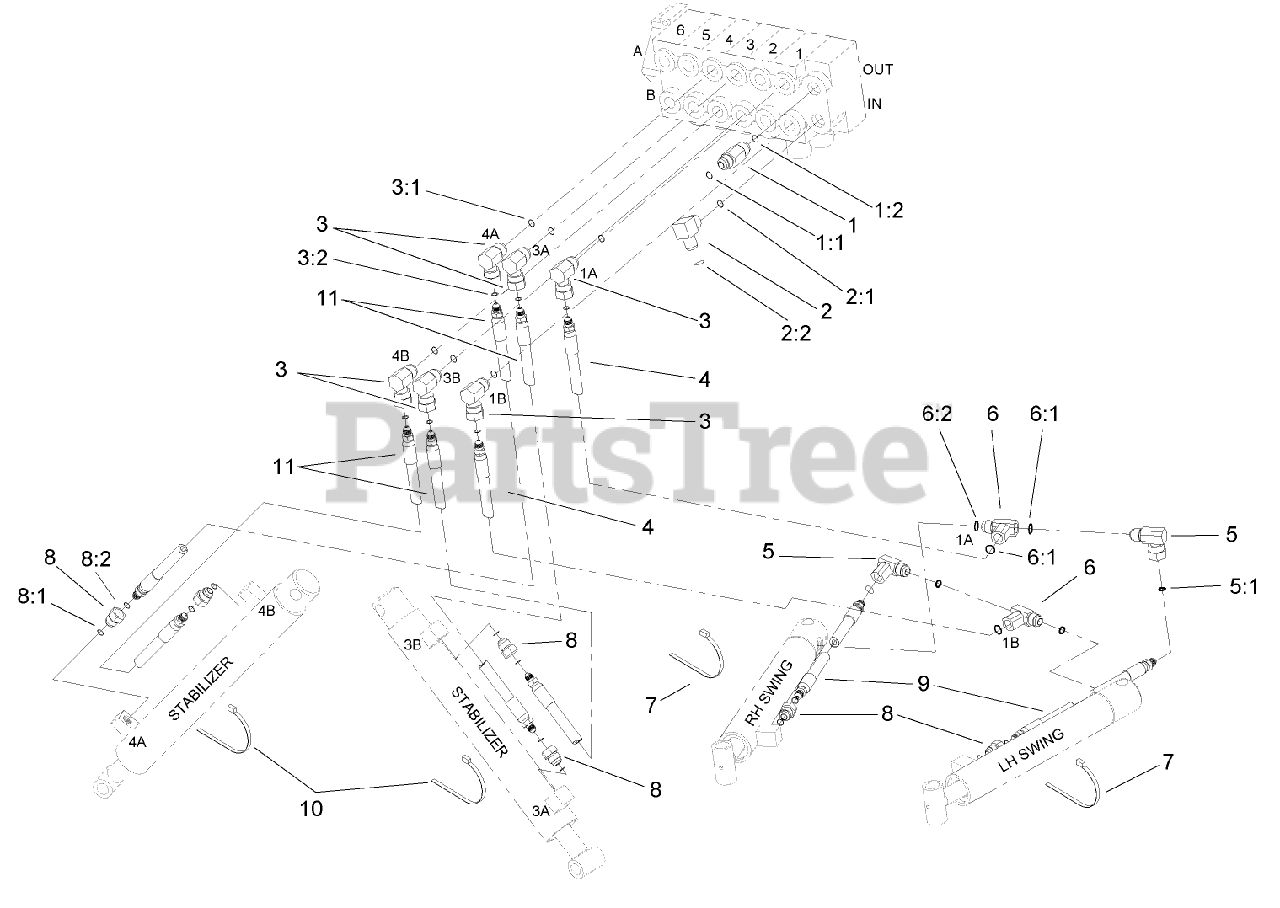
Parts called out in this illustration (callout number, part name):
1	FITTING-STRAIGHT
1:1	O-RING
1:2	O-RING
2	FITTING-ELBOW 90
2:1	O-RING
2:2	O-RING
3	FITTING-ELBOW 90
3:1	O-RING
3:2	O-RING
4	HOSE-HYD
5	FITTING-ADAPTOR
5:1	O-RING
6	FITTING-TEE
6:1	O-RING
6:2	O-RING
7	TIE-CABLE
8	FITTING-STRAIGHT
8:1	O-RING
8:2	O-RING
9	HYDRAULIC HOSE ASM
10	TIE-CABLE
11	HYDRAULIC HOSE ASM
